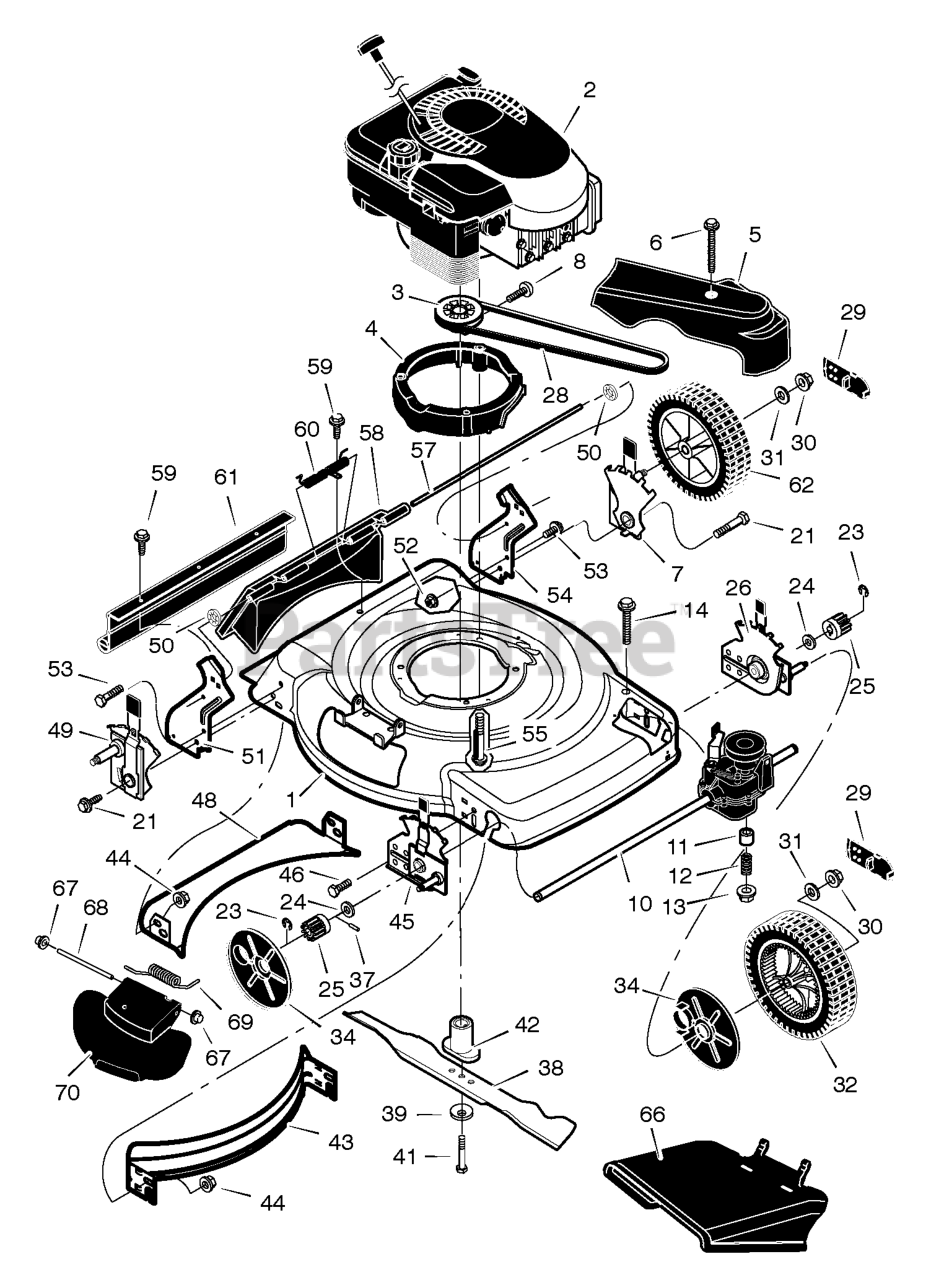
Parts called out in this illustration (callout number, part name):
1	Housing
2	Engine *
3	Pulley, Drive
4	Spacer, Engine
5	Cover, Belt (Black)
6	Screw
7	Adjuster, Left Rear Height
8	Screw
10	Transmission *
12	Spring, Compression
13	Nut
14	Bolt
21	Bolt
25	Gear, Pinion
26	Adjuster, Left Front Height
29	Cap, Hub
30	Nut, Flange
31	Washer
32	Wheel & Tire, Front *
34	Cover, Dust
37	Pin, Drive
38	Blade
39	Washer, Belleville
42	Adapter, Blade
43	Baffle, Front
44	Nut, Flange
45	Adjuster, Right Front Height
46	Bolt
48	Baffle, Rear
49	Adjuster, Right Rear Height
50	Retainer, Push
51	Bracket, Right Handle
52	Nut, Flange
53	Bolt
54	Bracket, Left Handle
55	Bolt, Engine
57	Rod, Pivot
58	Door, Rear (Black)
60	Spring
61	Guard, Rear
62	Wheel & Tire, Rear *
66	Deflector, Chute (Black)
67	Push On Cap
68	Rod, Pivot
69	Spring, Torsion
70	Cover, Mulch (Black)
